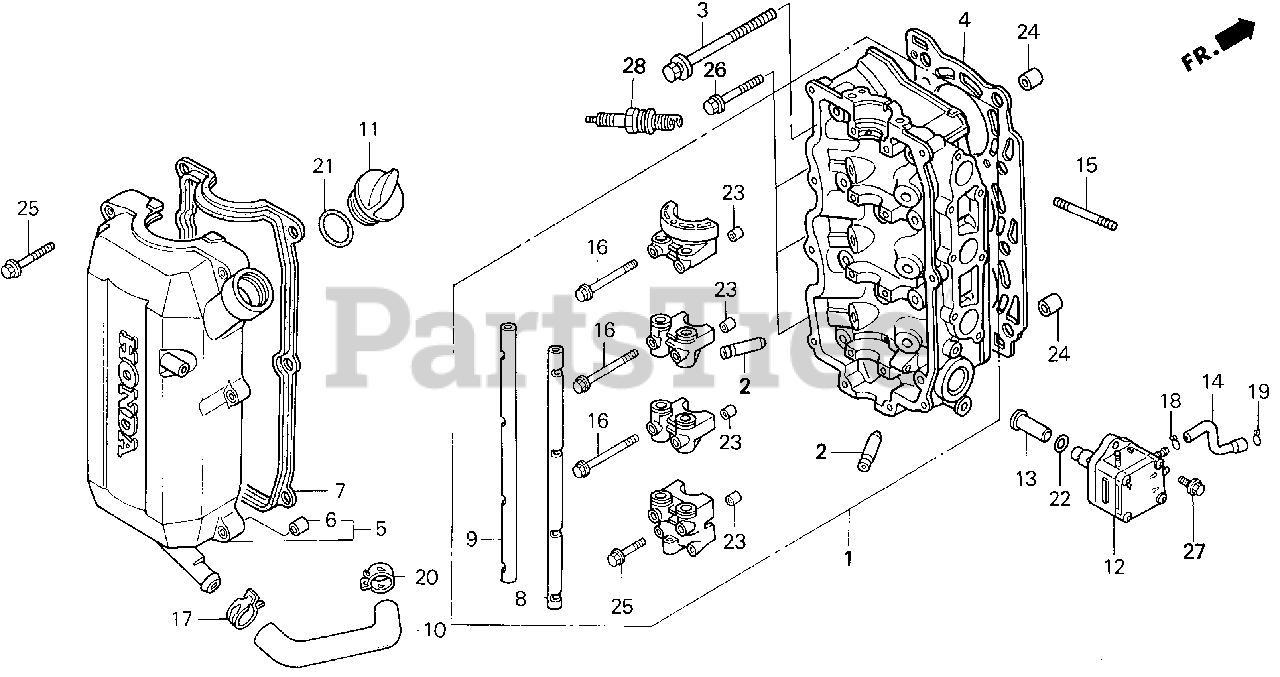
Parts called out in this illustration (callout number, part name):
1	CYLINDER HEAD ASSY. *NH8* (DARK GRAY)
2	GUIDE, VALVE (OS 0.52) Use up to Engine SN 1011643.
2	GUIDE, VALVE (0.25)
3	BOLT-WASHER (10X85)
4	GASKET, CYLINDER HEAD
5	COVER, CYLINDER HEAD
6	COLLAR, HEAD COVER
7	GASKET, HEAD COVER
8	SHAFT, IN. ROCKER ARM
9	SHAFT, EX. ROCKER ARM
10	TUBE, OIL
11	CAP, OIL (YELLOW)
12	PUMP ASSY., FUEL
13	LIFTER, FUEL PUMP
14	TUBE B, FUEL
15	BOLT, STUD (6X28)
16	BOLT, FLANGE (6X70)
17	CLAMP, TUBE (D22)
18	CLIP, TUBE (B10)
19	CLIP, TUBE (B12)
20	CLAMP, TUBE (D18.8)
21	O-RING (26X2.7)
22	O-RING (20.8X2.4)
23	PIN, DOWEL (8X14)
24	PIN, DOWEL (6X10)
25	BOLT, FLANGE (6X35)
26	BOLT, FLANGE (8X40)
27	BOLT, FLANGE (6X20)
28	SPARK PLUG (DR7EA) (NGK)
28	SPARK PLUG (X22ESR-U) (DENSO)
